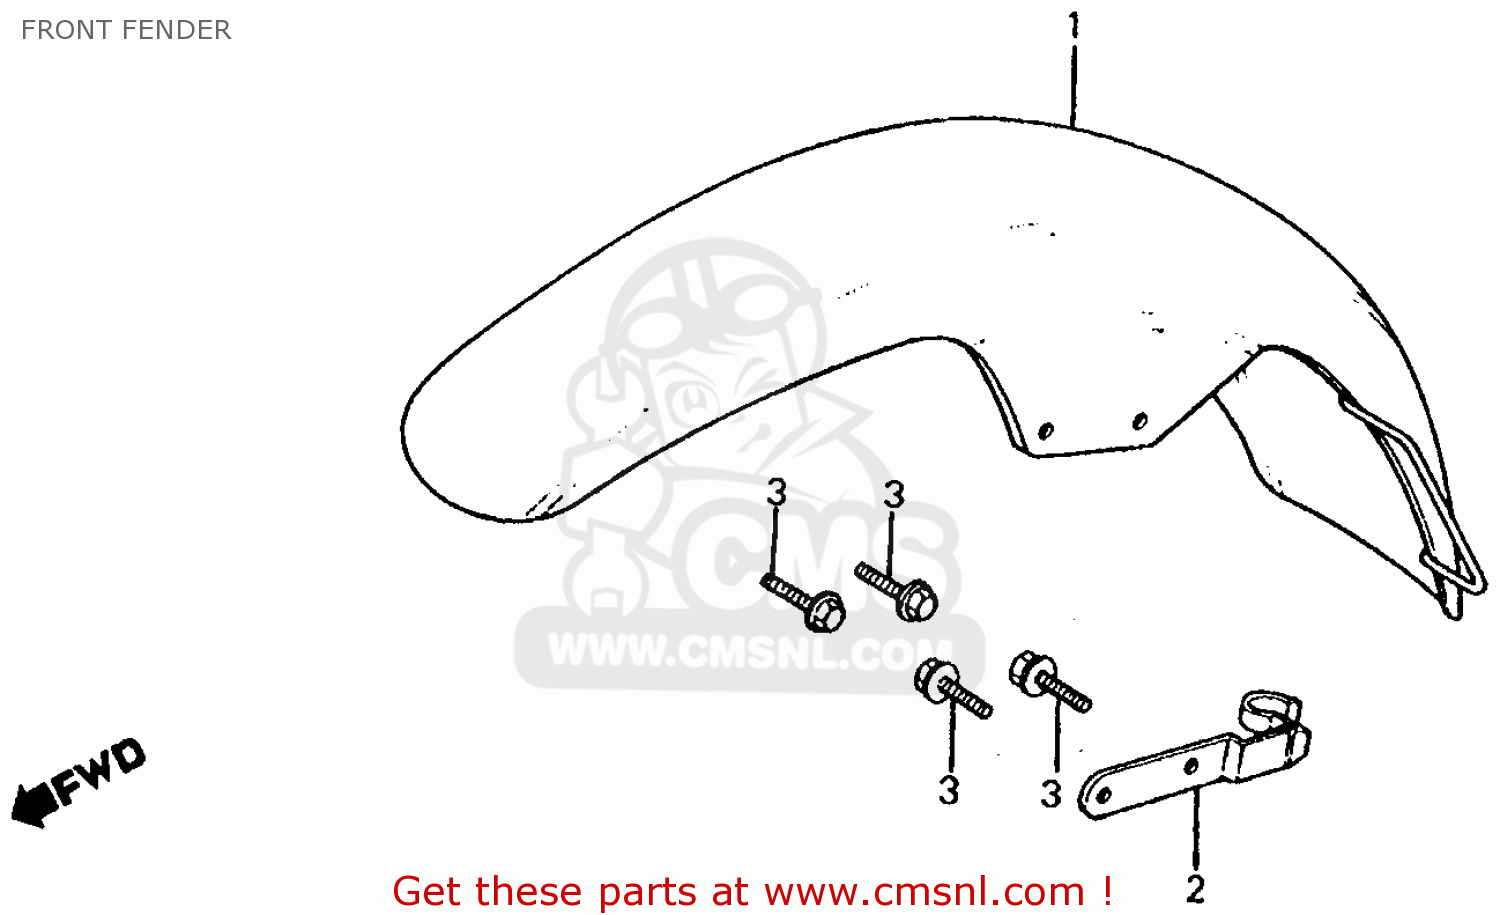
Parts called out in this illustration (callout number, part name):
1	FENDER COMP,FR,
2	CLAMP,FR,BRK.HOSE
3	BOLT,FLANGE 6X14
